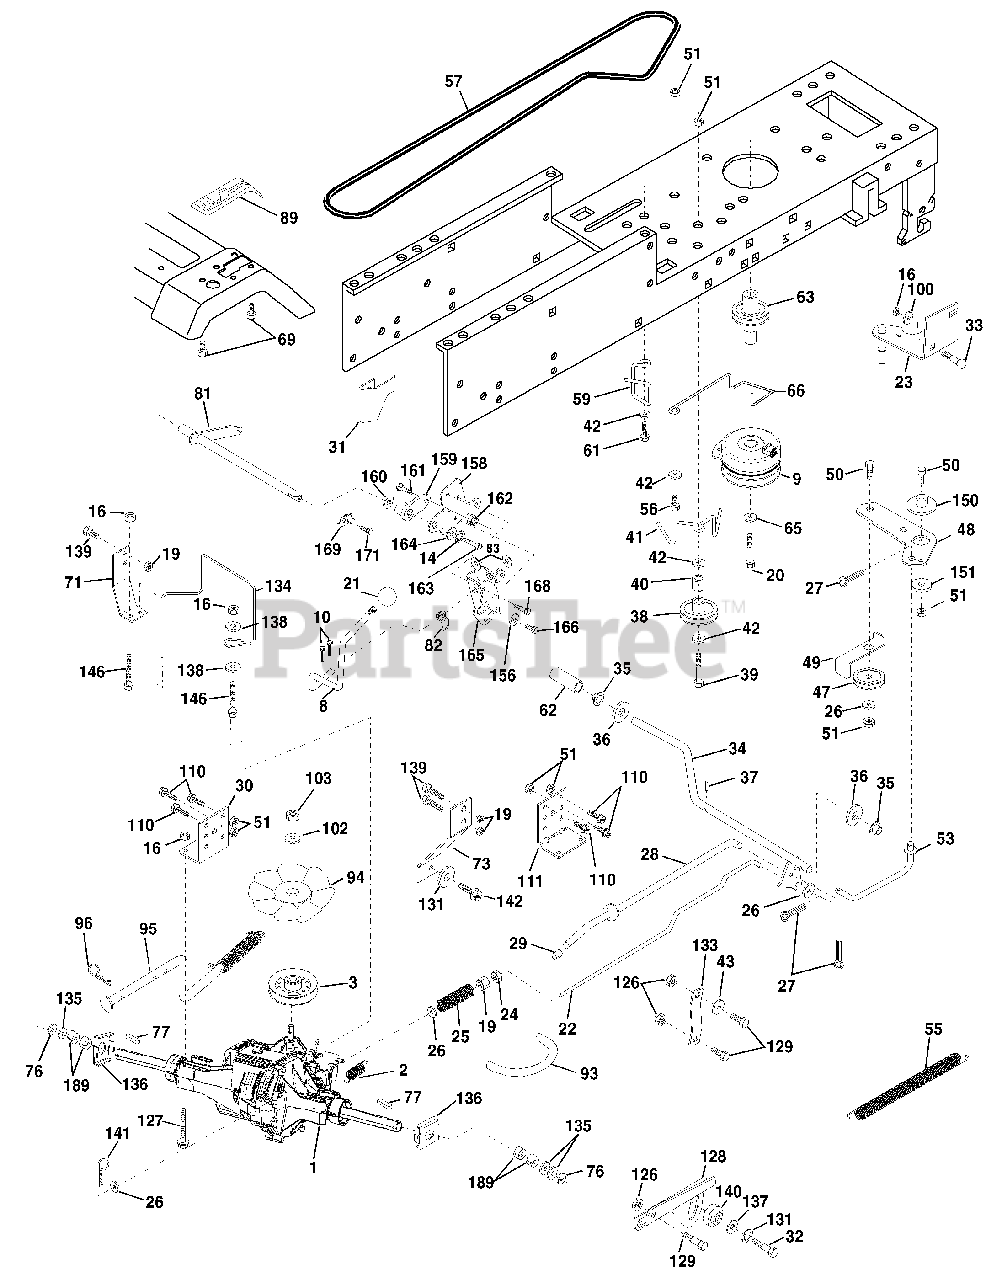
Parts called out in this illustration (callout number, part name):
2	Spring, Brake Return
3	Pulley, Transaxle
8	Rod Shift Fender Adjust
9	Clutch Elect EVX 80 lb.
10	Pin, Cotter 1/8 x 1
14	Washer Lock Hvy Helical
16	Nut, Lock Hex w/Ins. 5/16-18 UNC
19	Nut, Lock Hex w/Washer 3/8-16 UNC
20	Bolt Hex 7/16-20 x 4-1/4 5 Ga.
21	Knob Deluxe 1/2-13 Unc
22	Rod, Brake
23	Bracket Asm Clutch Mtg. Evx
24	Nut, Hex Jam 3/8-16
25	Spring, Rod, Brake
26	Washer 13/32 x 13/16 x 16 Ja.
27	Pin, Cotter 1/8 x 3/4
28	Rod, Brake, Park
29	Cap, Brake Parking Black
30	Bracket, Transaxle
31	Keeper, Belt, Transaxle,
32	Hex Bolt 5/16-18 UNC x 3/4
33	Bolt Rdhd Sqnk 5/16-18 Unc x 3/4
34	Shaft, Foot Pedal
35	Bearing Nylon
37	Pin,Roll
38	Idler, Flat
40	Spacer, Split
41	Keeper, Idler
42	Washer 13/32 x 13/16 x 12 Ja.
43	Washer 11/32 x 5/8 x 12 Ga.
47	Pulley, Idler
48	Bellcrank Clutch Grnd Drv Stl
49	Retainer, Belt
50	Bolt, Hex 3/8-16 x 1-1/2
51	Nut, Crownlock 3/8-16
53	Link, Clutch
55	Spring, Return, Clutch
56	Bolt, Hex 3/8-16 UNC x 1-1/4
57	V-Belt Drive
59	Keeper Belt Centerspan
61	Screw Thdrol 3/8-16 x 3/4
62	Cover, Foot Pedal
63	Engine Pulley
65	Washer
66	Keeper, Belt Engine
71	Torque Fastener L.H.
73	Torque Fastener R.H.
74	Spacer, Split
77	Key, Square
81	Shaft Asm Cross Tapered
82	Spring, Torsion
83	Washer 17/32 x 3/4 x 16 Ja.
89	Console, Shift
95	Control Assembly Bypass Hydro
96	Retainer, Spring 1"
100	Washer 11/32 x 3/4 x 16 Ja.
102	Washer .501 x 1.50D
103	Nut Hex Jam Toplock 1/2-20 UNF
110	Bolt, Hex 3/8-16 UNC x 3/4
127	Bolt, Hex 5/16-18 UNC x 3
129	Bolt 5/16-18 UNC
131	Push Nut 5/16
133	Link Transaxle Hydro 3000
134	Belt, Guide
135	Washer 1-1/32 x 1-5/8 x 16 Ja.
137	Washer 11/32 x 3/4 x 12 Ja.
138	Washer 11/32 x 1.25 x 16 Ja.
139	Bolt, Hex 3/8-16 UNC x 3/4
142	Bolt 5/16 x 24 x 1
146	Bolt Hex Flghd 5/16-18 x 2-1/4
150	Bushing Bellcrank Grd Drive
151	Washer 13/32 x 2 x 10 Ja.
156	Washer Srrted 5/16ID x 1.125
158	Bracket Shift Mount
159	Hub Tapered Flange Shift Lt
160	Washer 29/32 x 1-1/4 x 16 Ga
161	Bolt Rdhd Sqnk 1/4-20 x 3/4 Gr 5
162	Nut Crownlock 1/4-20 Unc
163	Bolt Hex Fin 1/4-20 Unc x 1 Gr 5
164	Washer 5/8 x .281 x 10 Ga
165	Bracket Pivot Lever
166	Screw 5/16-18 x 5/8
168	Bolt Shoulder 5/16-18 x .561
169	Plate Fastening Lt
171	Screw Thdrol 3/8-16 x 1/2 Ty-Tt
